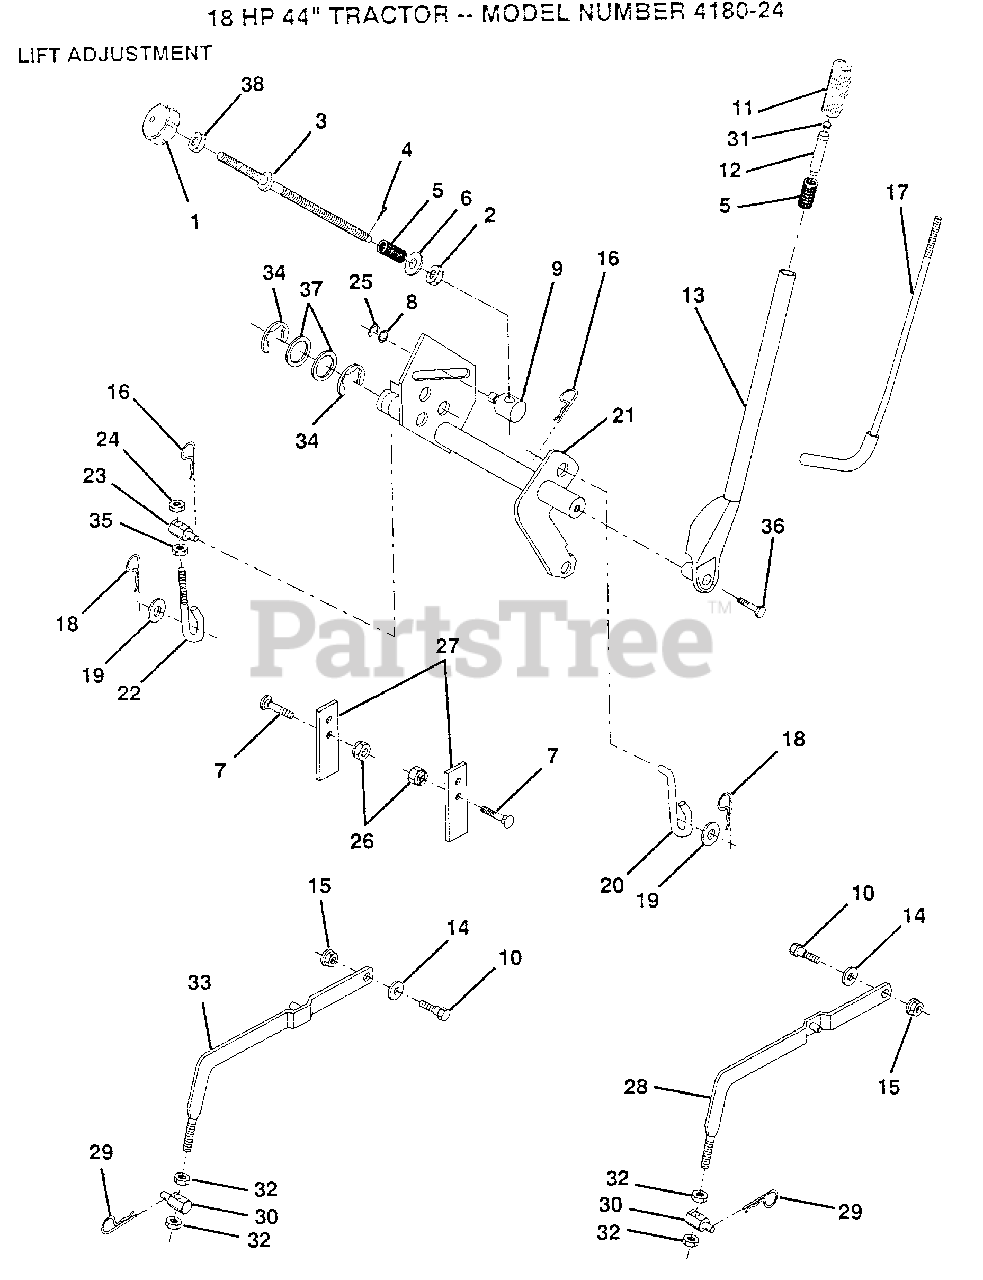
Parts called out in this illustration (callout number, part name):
1	HDLE ADJ LIFT
2	NUT T
3	ROD LIFT LT
5	SPRING T
6	WASHER
8	WASHER
9	TRUNION LT
10	"BOLT, SHOULDER LT"
11	GRIP
14	WASHER T
15	NUT SPECIAL T
17	LEVER ROD LT
18	SPRING.RETAINER
20	LIFT LINK LT
21	LIFT SHAFT ASM
22	PIVOT PIN T
25	KLIP RING
27	UPSTOP
28	RH SUSP ARM ASM
29	SPRING H
32	NUT
33	LH SUSP ARM ASM
34	E-RING
35	NUT
36	"BOLT,HEX"
37	WASHER
38	NUT
